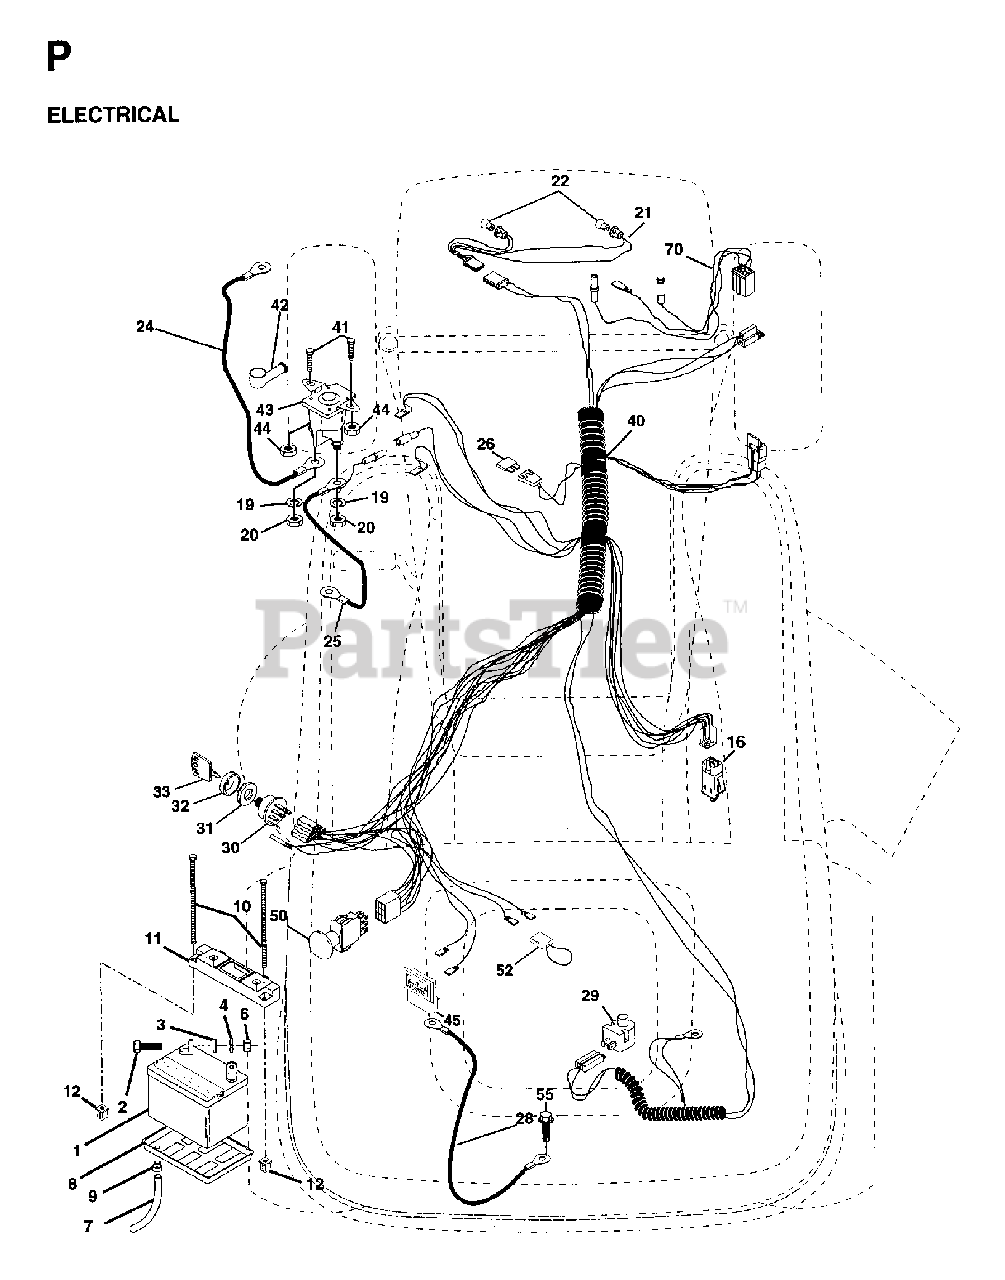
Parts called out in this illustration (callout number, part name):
1	BATTERY.DRY.30.AMP
3	WASHER
4	LOCKWASHER
6	NUT
7	PLASTIC TUBE
8	BATTERY TRAY T
9	HOSE CLAMP T
10	BOLT 1/4-20 X 7.5
11	BATTERY HOLDDOWN
12	NUT, PUSH NYLON 1/4" BATTERY
16	SWITCH INTERLOCK
19	LOCKWASHER
20	NUT
21	HARNESS ASM HDLIG
22	LIGHTBULB
24	BATTERY CABLE GT
25	CABLE BATTERY 6 GA 22" W/16W
28	CABLE GROUND 6 GA 21" 90T BLK
29	SWITCH SEAT
30	SWITCH.IGNITION.4.POSITION
31	NUT IGNITION
32	COVER SWITCH KEY
40	IGN HARNESS
42	TERMINAL COVER
43	SOLINOID
50	SWITCH PTO 3 PDT
52	WIRE PROTECTION LOOP
55	SCREW LT
